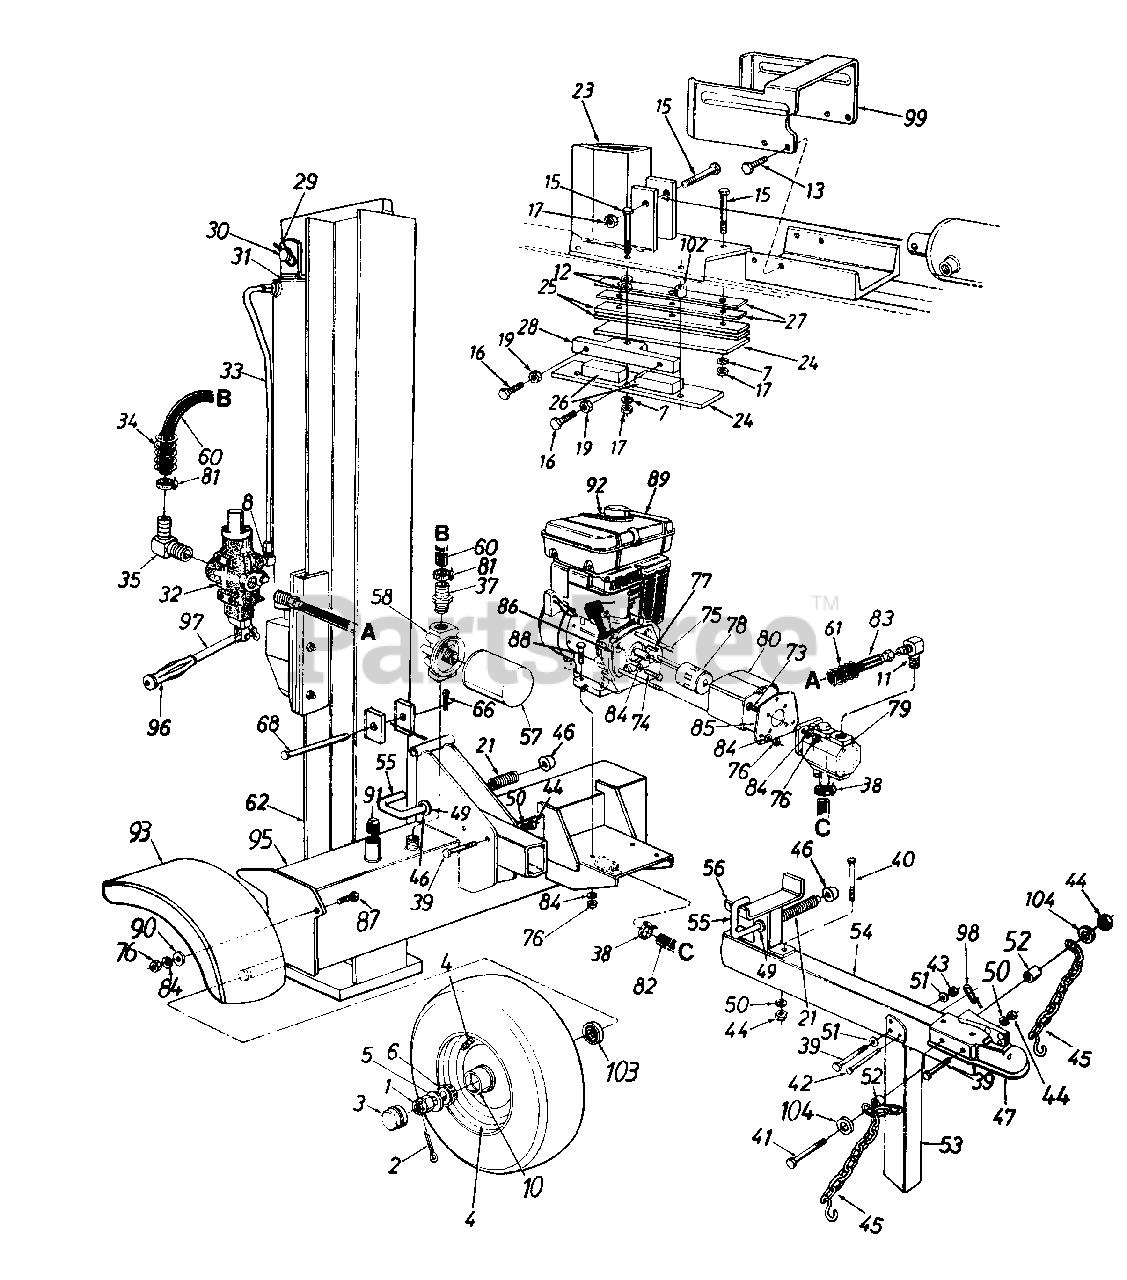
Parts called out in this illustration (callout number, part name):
1	Slotted Nut 3/4-16 Thd.
2	Cotter Pin 5/32" Dia.
3	Hub Cap
5	Fl-Wash. .76" I.D. x 1.5" O.D.
6	Bearing Cone
7	L-Wash. 1/2" I.D.
8	90ø Solid Male Adapter
9	Pipe Nipple 1/2 NPT
10	Bearing Cup
11	90ø Male Adapter
12	Fl-Wash. .531" I.D. x .94" O.D.
13	Hex Cap Scr. 3/8-16 x 1" Lg.
15	Hex Bolt 1/2-20 x 2.75" Lg. (Grade 8)
16	Hex Bolt 3/8-24 x 1.5" Lg.
17	Hex L-Nut 1/2-20 Thd.
19	Hex Jam Nut 3/8-24 Thd. (Grade 5)
21	Comp. Spring 4" Lg.
29	Cotter Pin
30	Clevis Pin
33	Metal Pressure Tube
34	Hose Guard
35	REturn Elbow
37	3/4" Hose Barb.
38	Hose Clamp 1.5" O.D.
39	Hex Bolt 3/8-16 x 3" Lg. (Grade 8)
40	Hex Bolt 3/8-16 x 4" Lg.
41	Hex Bolt 3/8-16 x 4.25" Lg.
42	Clevis Pin 5/16 x 2.5" Lg.
43	hex L-Nut 3/8-16 Thd.
44	hex Nut 3/8-16 Thd.
45	Chain--Tow Hitch
46	Push Cap
47	Hitch Coupler
49	Fl-Wash. .635" I.D. x .93" O.D.
50	L-Wash. 3/8" I.D.
51	Fl-Wash. .406" I.D. x .75" O.D.
52	Spacer .445" Lg.
55	Locking Rod
57	Filter Element
58	Filter Head
60	Return Hose 3/4" I.D. x 44" Lg.
61	Hose Guard
68	Hinge Pin 1/2 x 4.8" Lg.
73	Hex Bolt 5/16-24 x 1" Lg.
74	Hex Bolt 5/16-24 x .62" Lg.
75	Hex Bolt 5/16-24 x 4" Lg.
76	Hex Nut 5/16-24 Thd.
77	Sq.-Key 3/16" x .75" Lg.
78	Flexible Coupling
79	Gear Pump
80	Coupling Shield
81	Hose Clamp 5/8"
82	Suction Hose 1" I.D.
83	High Pressure Hydraulic Hose 48"
84	L-Wash. 5/16" I.D.
87	Hex Bolt 5/16-24 x .75" Lg.
88	Hex Bolt 5/16-24 x 1.75" Lg.
89	Engine
90	Fl-Wash. .344" I.D. x .875" O.D.
91	L-Vent Pipe Plug
92	Spark Plug Boot
97	Control Handle
98	Spring Pin
102	Spacer 1/2" I.D. x .86" Lg.
103	Bearing Seal Only
104	Fl-Wash. 3/8" I.D. x .87" O.D.
